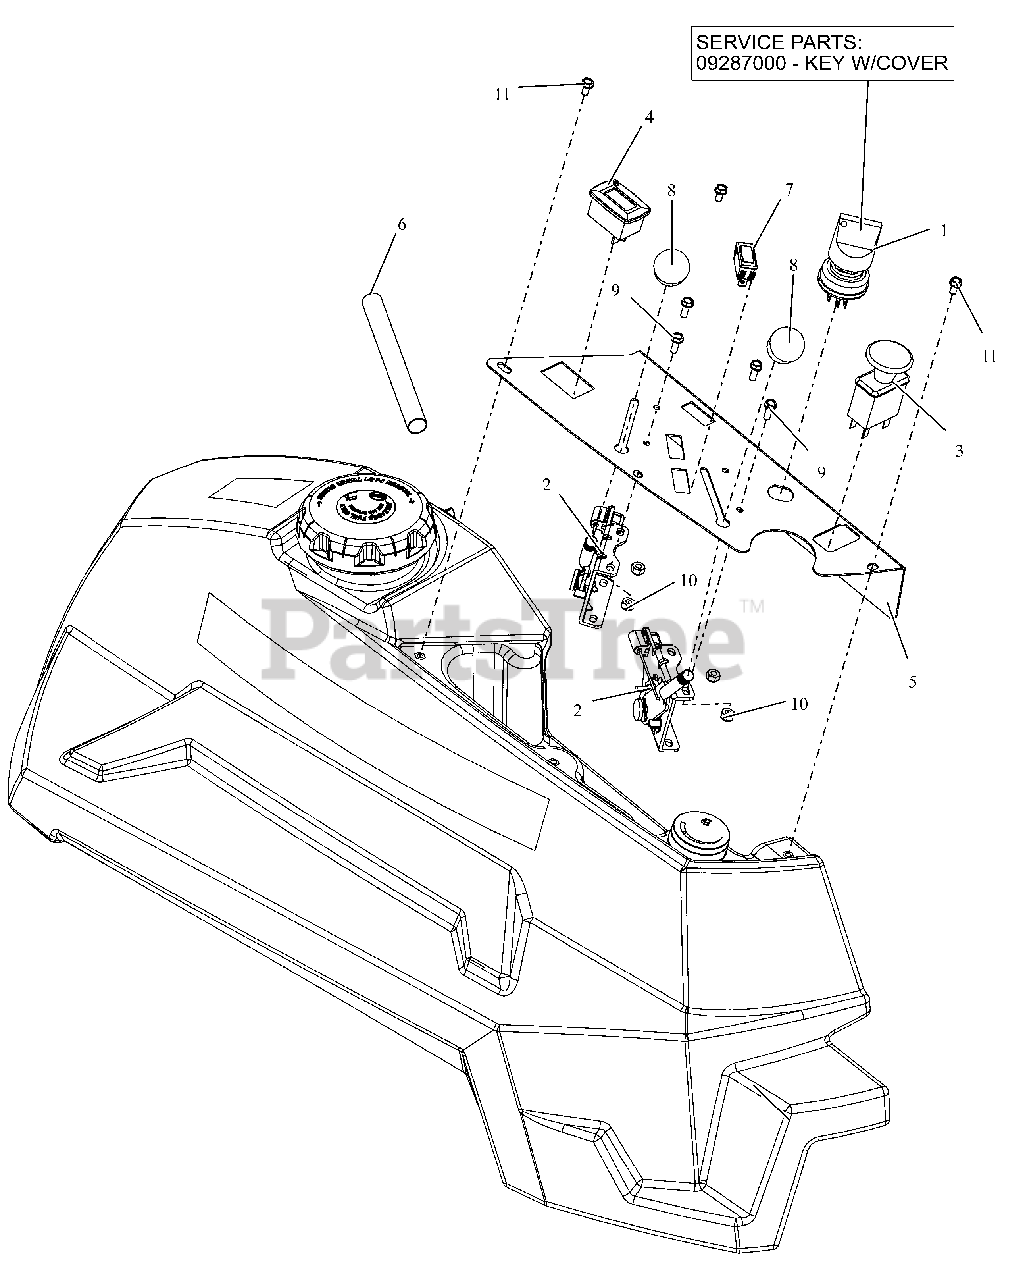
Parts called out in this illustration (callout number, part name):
1	SWITCH, IGNITION
1	KEY, W/ SHIELD
2	CABLE, PRO-CTRL 43.00"
3	SWITCH, CLUTCH
4	METER, HOUR W/MAINTENANCE
5	PT400 CONTROL PANEL - RED
6	SLEEVE, THERMAL 6"
7	LIGHT, INDICATOR (RED)
8	KNOB-CONTROL-BLACK .38-16X.50
9	BLT, HWH #10-24X.50 ZCC
10	NUT-LK-NYL #10-24 G2 ZCC
11	SCR-MCH 10-24X.38 HWHSTAINLESS
